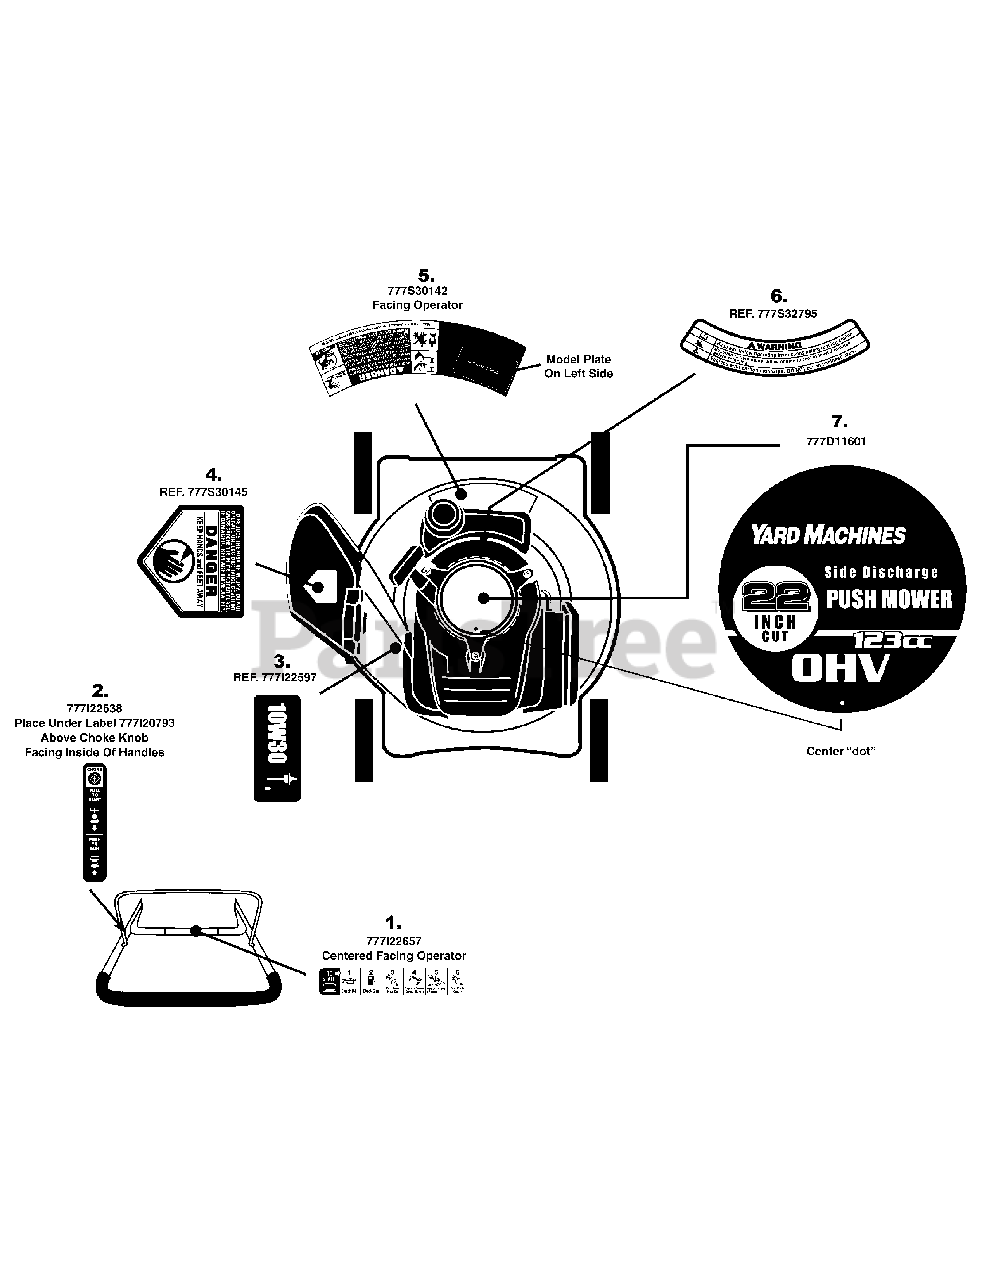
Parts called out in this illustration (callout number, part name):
1	LABEL-MOWER HANDLE
2	LABEL-MOWER HANDLE:CHOKE START/RUN
3	LABEL:MOWER SHROUD
4	LABEL
5	LABEL-DANGER CURVE
6	LABEL
7	LABEL-MOWER SHROUD YARD MACHINES
